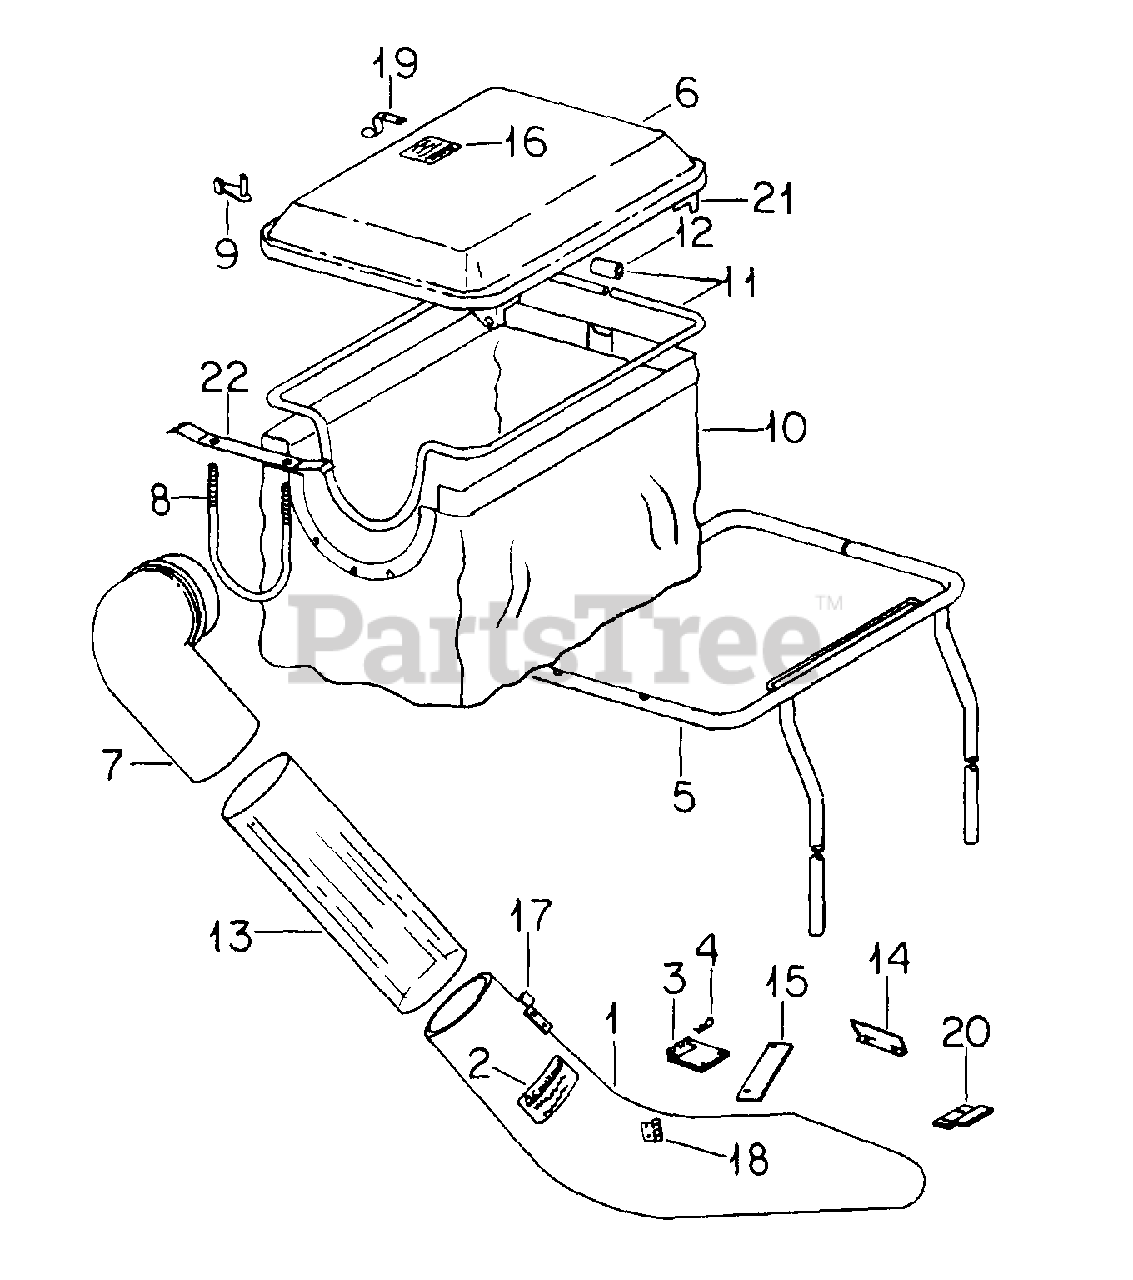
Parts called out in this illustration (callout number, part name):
1	CHUTE ASSY, DISCHARGE
2	PRODUCT GRAPHIC, CAUTION - GRASS CATCHER
3	HINGE ASSY, CHUTE
4	PIN, .094 X 2.402 CAD QA COT
5	FRAME ASSY, BAGGER
6	COVER ASSY, GRASS BAG
7	ELBOW, CHUTE
8	BRACKET, ELBOW
12	SLEEVE, BAG FRAME
13	SHEET, CONNECTING TUBE
14	WING, 28 IN. MOWER BLADE
15	FLANGE, LOCATOR
16	PRODUCT GRAPHIC, CAUTION - MOWER INSTRUCTIONS
17	RETAINER, TUBE
18	HINGE, LEAF CHUTE
20	SUPPORT, FRONT LOCATOR
21	HINGE, COVER
22	SPRING, BAG RETAINER
